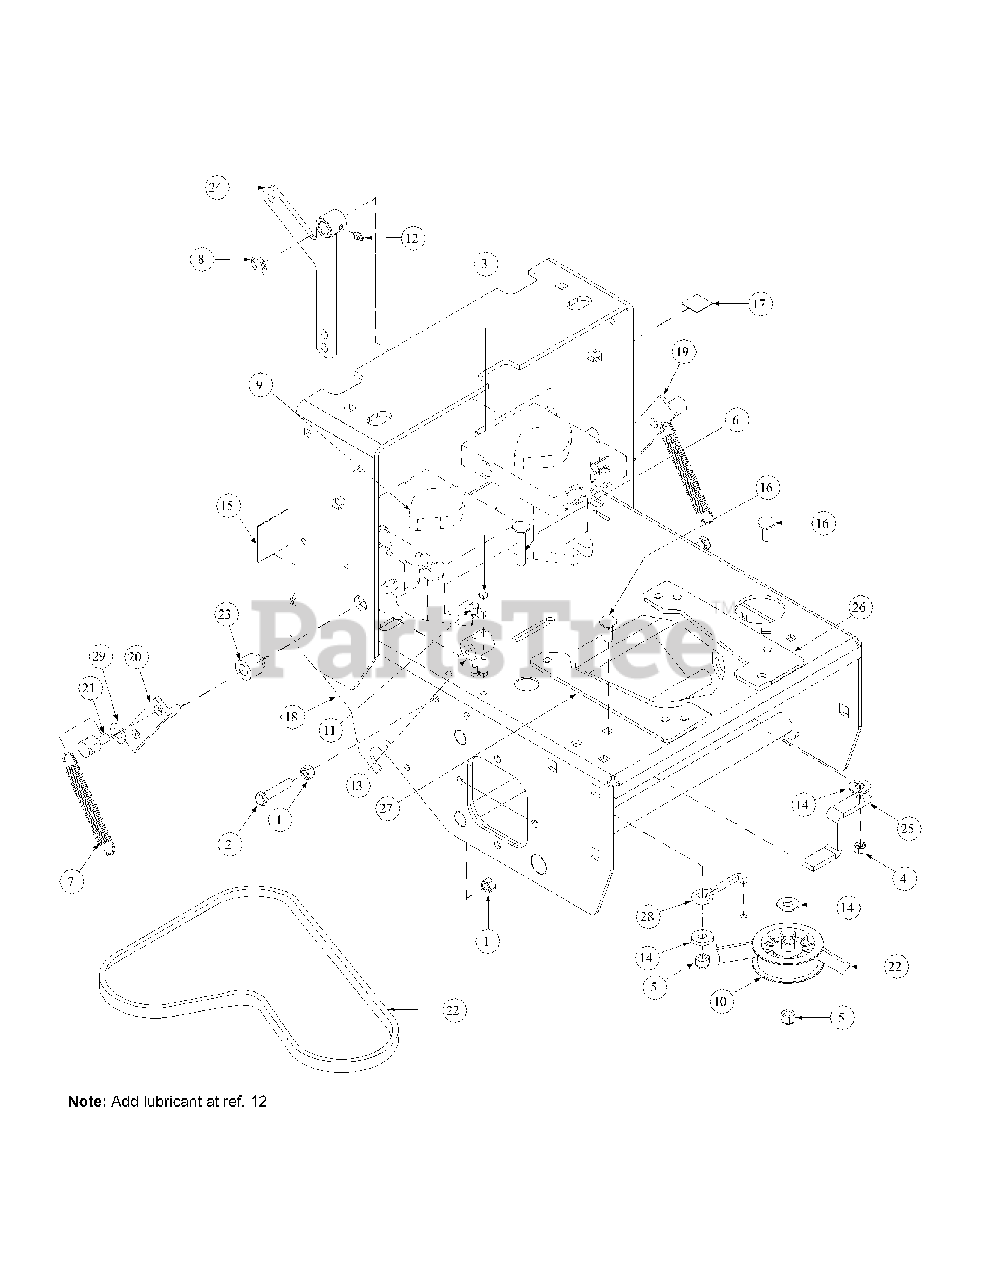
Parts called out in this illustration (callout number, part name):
1	Nut, Hex, 3/8-16 Grade
2	Cap Screw, 3/8-16 x 1-3/4" Grade 5
3	Cap Screw, Square Head Set, 1/4-20
4	Nut, 5/16-18, Nylock
5	Nut, L, Nylon Insert, 3/8-16 Grade A
6	Carriage Bolt, 3/8-16 x 2 Grade 5
7	Spring, Music Wire, LE-093G-9, Plat
8	E-Ring, 5/8" #5113-62
9	Hydro Pump
10	Pulley, Flat Idler W/Adaptor
11	Screw, Cap, Square Head Set, 1/4-20
12	Grease Fitting, 1/4-28 x 3/16 STR
13	Coupling, Trunnion
14	Washer, Idler
15	Decal, "Made In America"
16	Carriage Bolt, 3/8-16 x1.25 Grade 5
17	Label, Mower, Warn, Open Belt Drive
18	Engine Base Assembly, Hydro
19	Hydro Pump Lever Assembly LH
20	Hyrdro Pump Lever Assembly RH
21	Pivot Belt Tightener
23	Bushing, Pump Lever,
24	Bellcrank Clutch
25	Belt Guide, Engine, 36/42/48
26	Spacer, Engine, Right Hand
27	Spacer, Engine, Left Hand
28	Belt Guide, 3.375
29	Flat Washer
